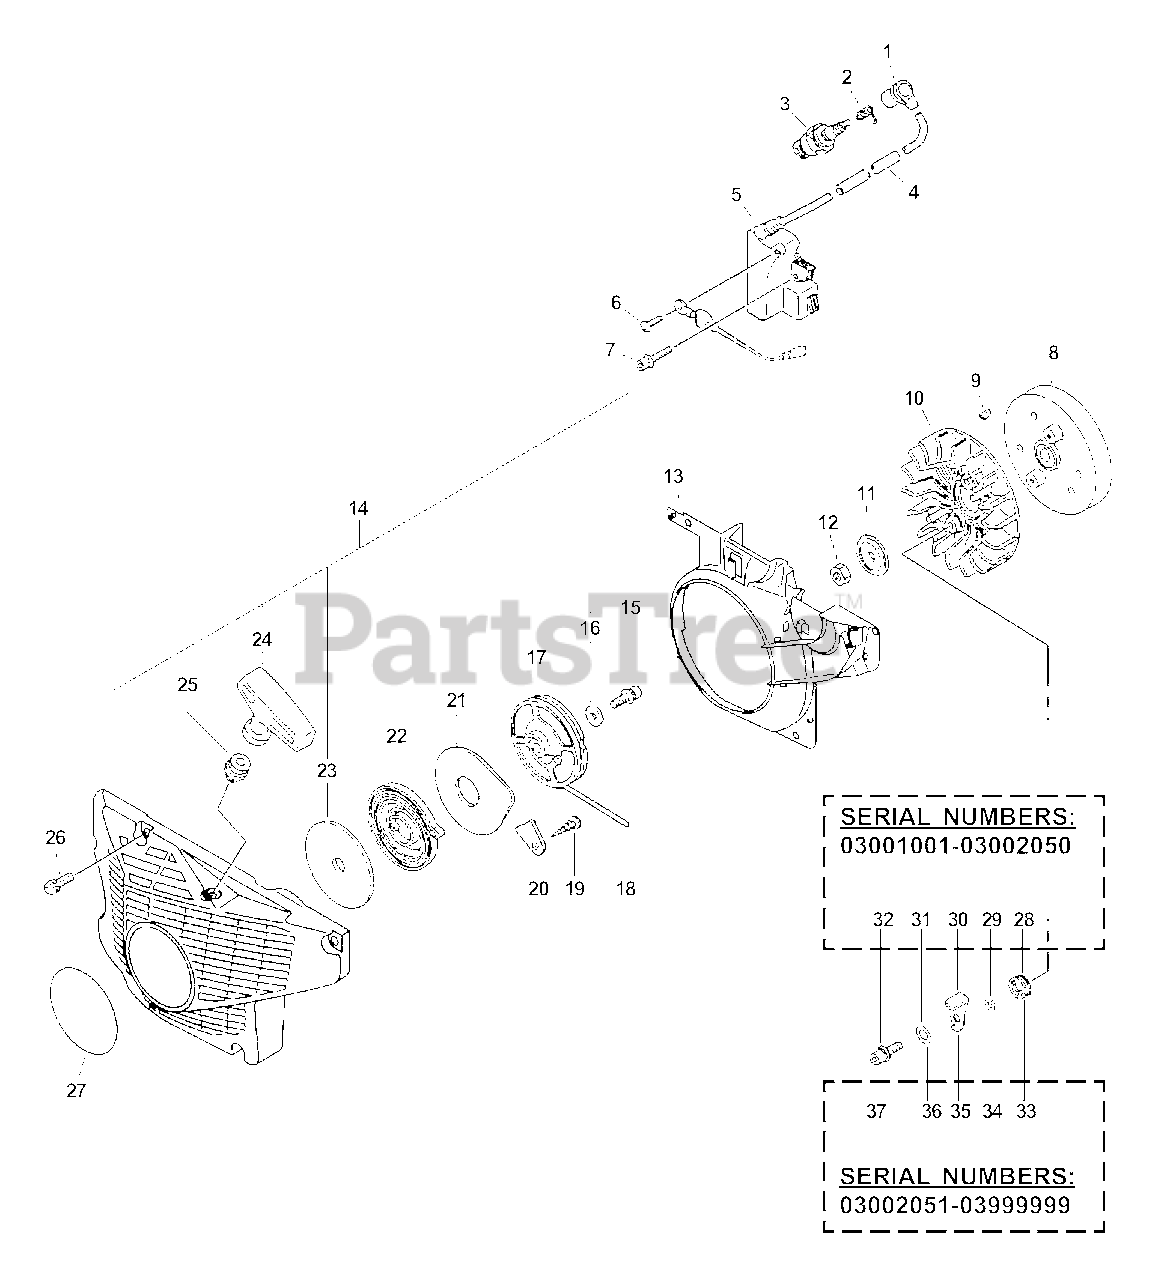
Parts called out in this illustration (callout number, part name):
1	CAP, SPARK PLUG
2	TERMINAL, SPARK PLUG CAP
3	SPARK PLUG -- BPM-7Y
5	COIL, IGNITION
6	SCREW - 4X8
7	SCREW - 4X20
8	FLYWHEEL
11	WASHER - CUP
13	COVER, FAN
14	STARTER ASSY
15	SCREW - 5X14
16	WASHER - 5
17	REEL, ROPE
18	ROPE, STARTER - 4X900
19	SCREW - 4X8
20	RETAINER, BRAKE BAND
21	PLATE, STARTER
22	SPRING, REWIND
23	PLATE, STARTER
24	GRIP, STARTER
25	GUIDE, ROPE
26	SCREW - 5X20
27	LABEL - ECHO
28	SPRING, RETURN
30	PAWL, STARTER
31	WASHER - 5
32	SCREW - 5X14
33	SPRING, RETURN
34	SPACER, PAWL
35	PAWL, STARTER
36	WASHER - 5
37	SCREW - 5X20
